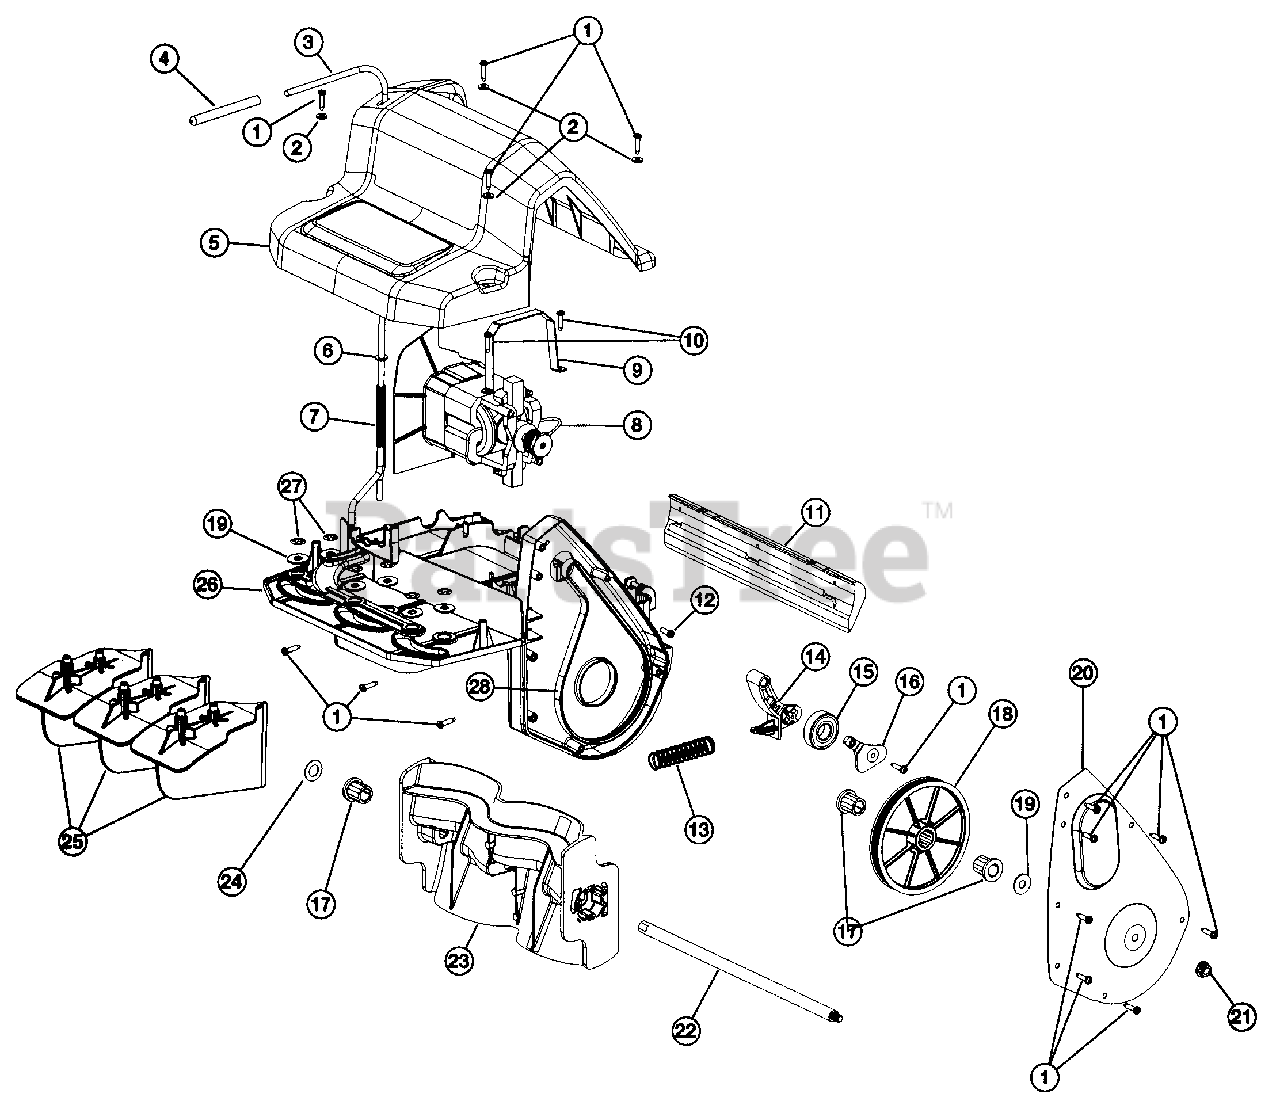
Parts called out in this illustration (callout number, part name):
3	Vane Control Handle
4	Grip
6	Washer
7	Spring
8	Motor Assm w/Baffle, Fan & Pulley
9	Motor Strap
10	Screw
11	Scraper
13	Spring
14	Idler Arm
15	Ball Bearing
16	Keeper
17	Flange Bearing
18	Driven Pulley
19	Washer
20	Belt Case Cover
21	Flange Lock Nut
22	Axle Auger
26	Snow Thrower Housing
27	Push Nut
28	Drive Belt
